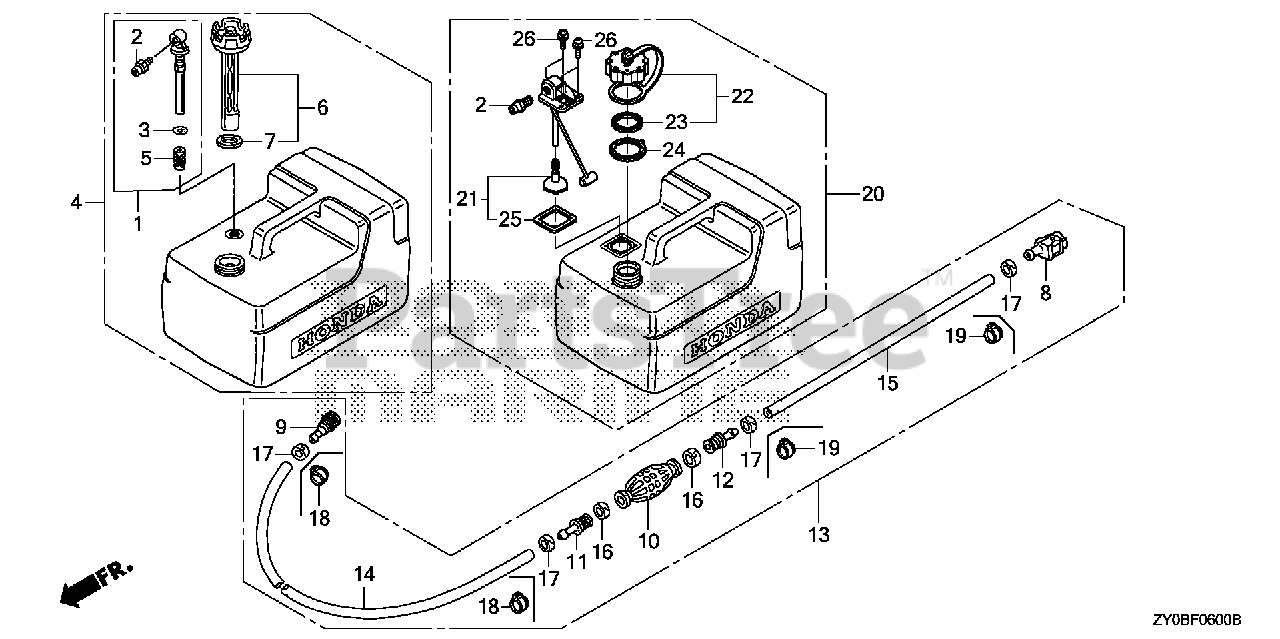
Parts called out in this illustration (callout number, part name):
2	FITTING, QUICK DISCONNECT
8	CONNECTOR ASSY., FUEL (A)
9	CONNECTOR, FUEL
10	BULB, PRIMER
11	VALVE, IN.
12	VALVE, OUTLET
13	TUBE ASSY., FUEL TANK
14	TUBE, FUEL LONG (7.3X2000)
15	TUBE, FUEL SHORT
16	BAND, TUBE CLIP (20MM)
18	CLAMP, FUEL TUBE (14.0)
19	CLAMP, FUEL TUBE (14.0)
20	TANK ASSY., FUEL
21	FILTER KIT, FUEL
22	CAP, FUEL FILLER
23	GASKET, FUEL CAP
24	RETAINER, PRESSURE RELIEF
25	GASKET, FUEL PICK-UP
26	BOLT-WASHER (5MM) (SEAL)
